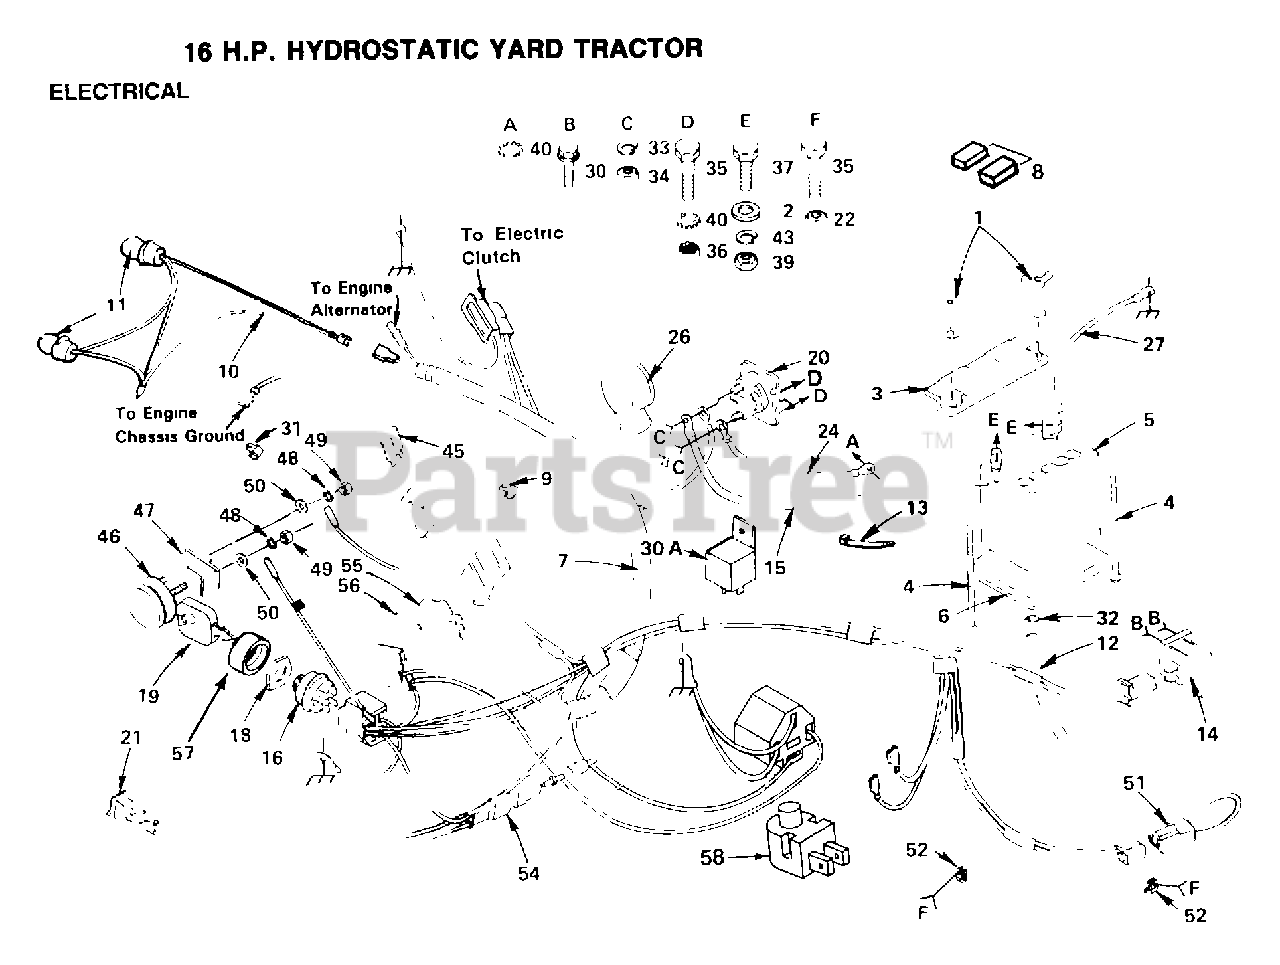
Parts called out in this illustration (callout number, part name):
2	WASHER
4	BOLT
6	"TRAY T, BATTERY"
8	"CAP,BATTERY "
10	HARNESS T
13	WIRE TIE
14	SWITCH-INTER. GT
15	CABLE-BATTERY T
19	KEY
21	SWITCH LT
24	"CABLE T, BATTERY"
27	CABLE T
30	SCREW
30A	RELAY ASSY T
31	CLIP T
32	HOSE CLAMP T
34	NUT
35	BOLT
36	NUT
37	BOLT LT
43	LOCKWASHER
45	FUSE HYT
46	AMMETER T
50	WASHER
52	CLIPT
55	SWITCH.PTO.T
56	HEX NUT T
58	SWITCH SEAT
60	"NUT,KEPS"
